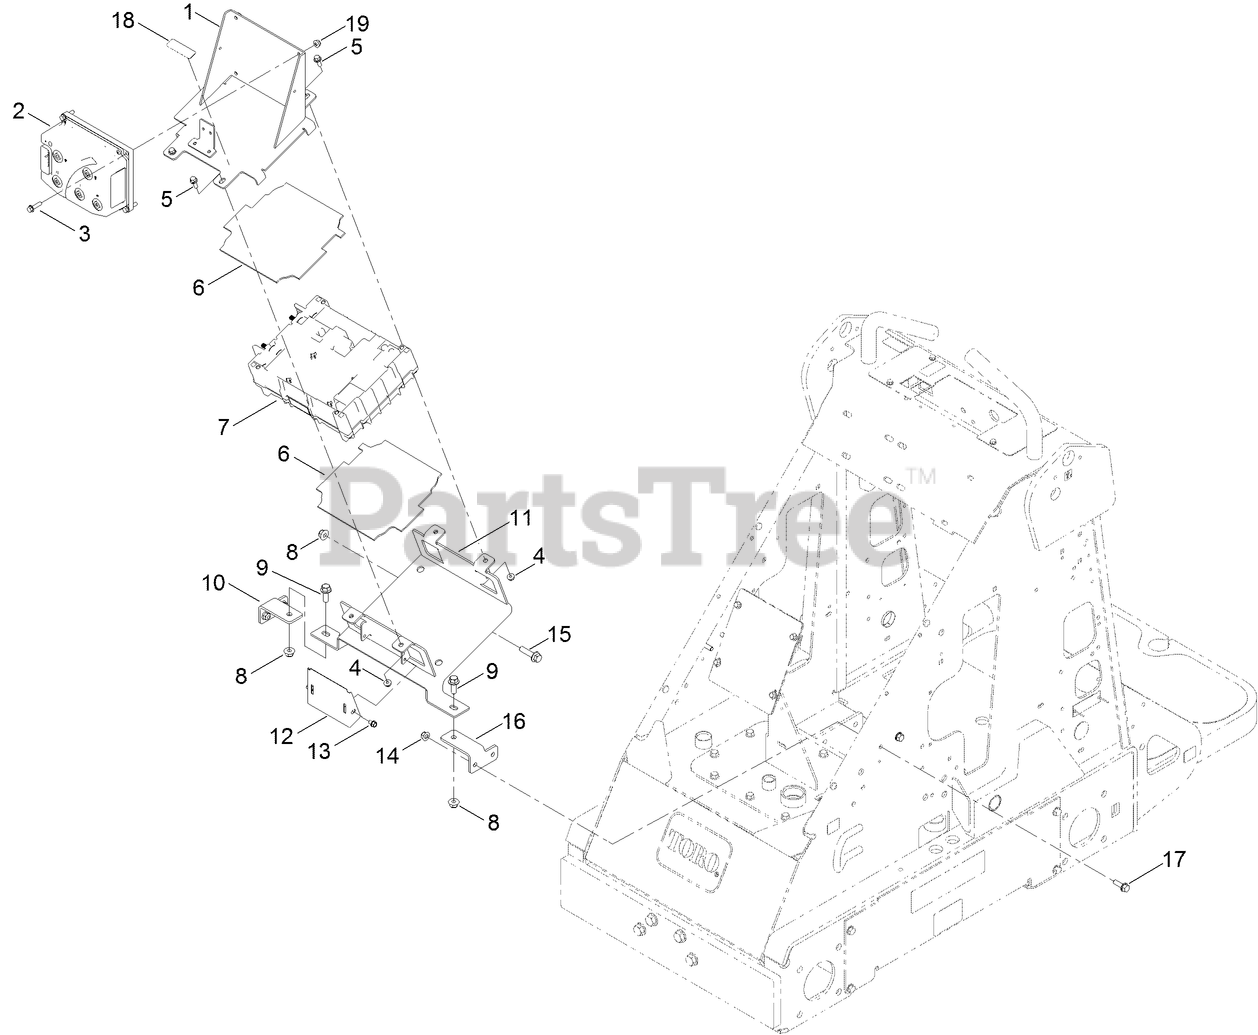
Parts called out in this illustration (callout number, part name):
1	MOUNT-CONTROLLER
2	INVERTER/CONTROLLER-48V,175Arms
3	SCREW-HHF
4	NUT-HF
5	SCREW-HHF
6	FOAM-BATTERY, BMS
7	CONTROLLER
8	NUT-HF, NI
9	SCREW-HHF
10	BRACKET-MOUNT, FRAME (RH)
11	MOUNT-BMS
12	ADAPTER, MEGA FUSE
13	SCREW-HWH
14	NUT-HF, NI
15	SCREW-HHF
16	BRACKET-MOUNT, FRAME (LH)
17	SCREW-HHF
18	DECAL-QUICK DISCONNECT
19	NUT-FLANGE, NI
